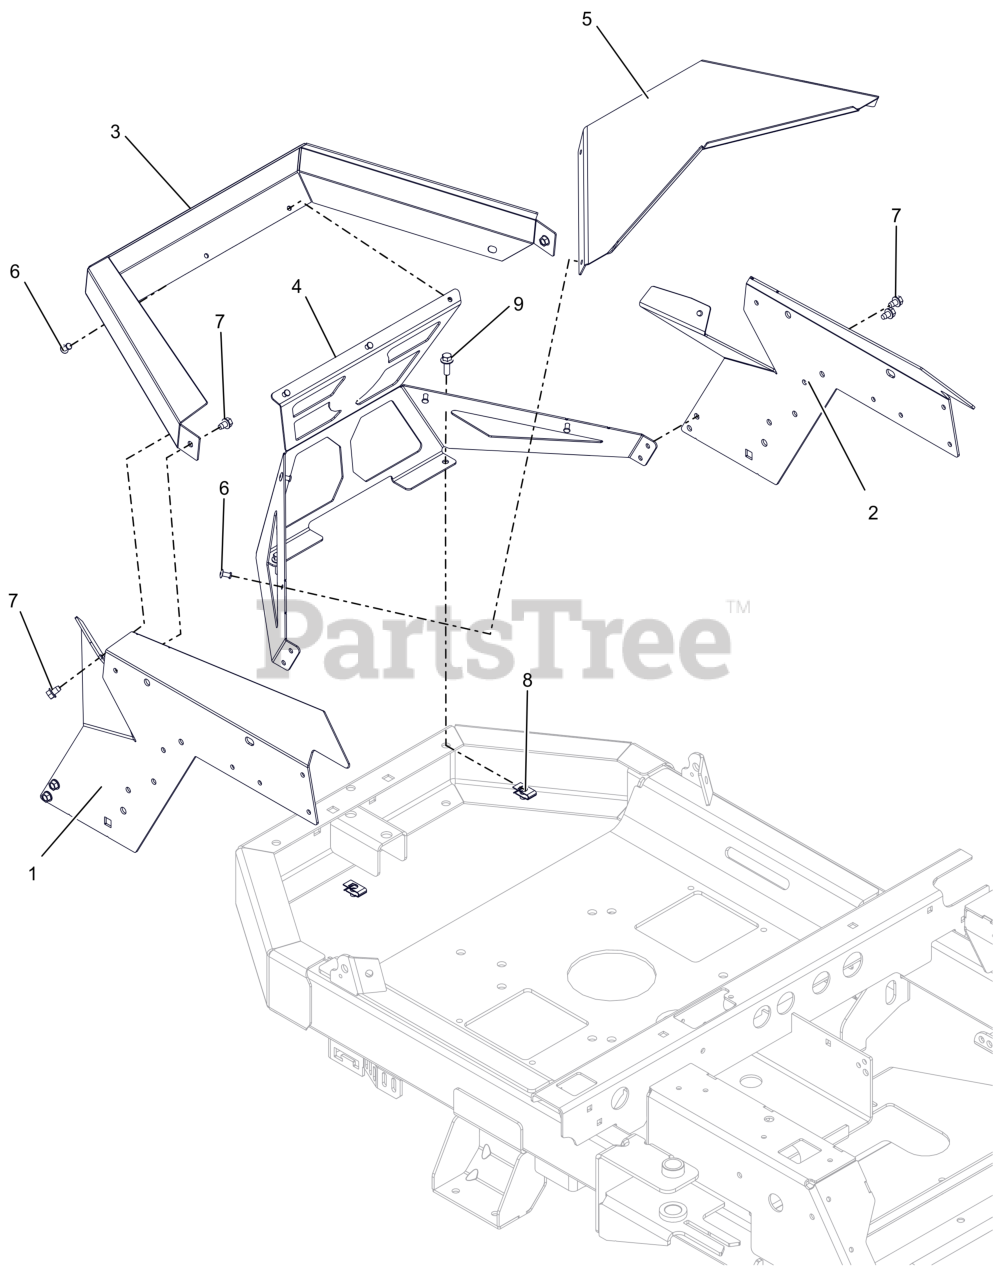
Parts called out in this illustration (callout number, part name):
1	PANEL, RIGHT REAR FENDER MOUNT
2	PANEL, LEFT REAR FENDER MOUNT
3	GUARD, ENGINE WRAP
4	GUARD, ENGINE
5	BAFFLE,ENGINE WRAP
6	RIVET, #66 STEEL POP PD BLACK
7	SCR,TAP .25-20X.375 HWH TR ZCC
8	NUT-RTNR .25-20X.56
9	BLT,HEX-FLG .25-20X.75 G5 BFP
